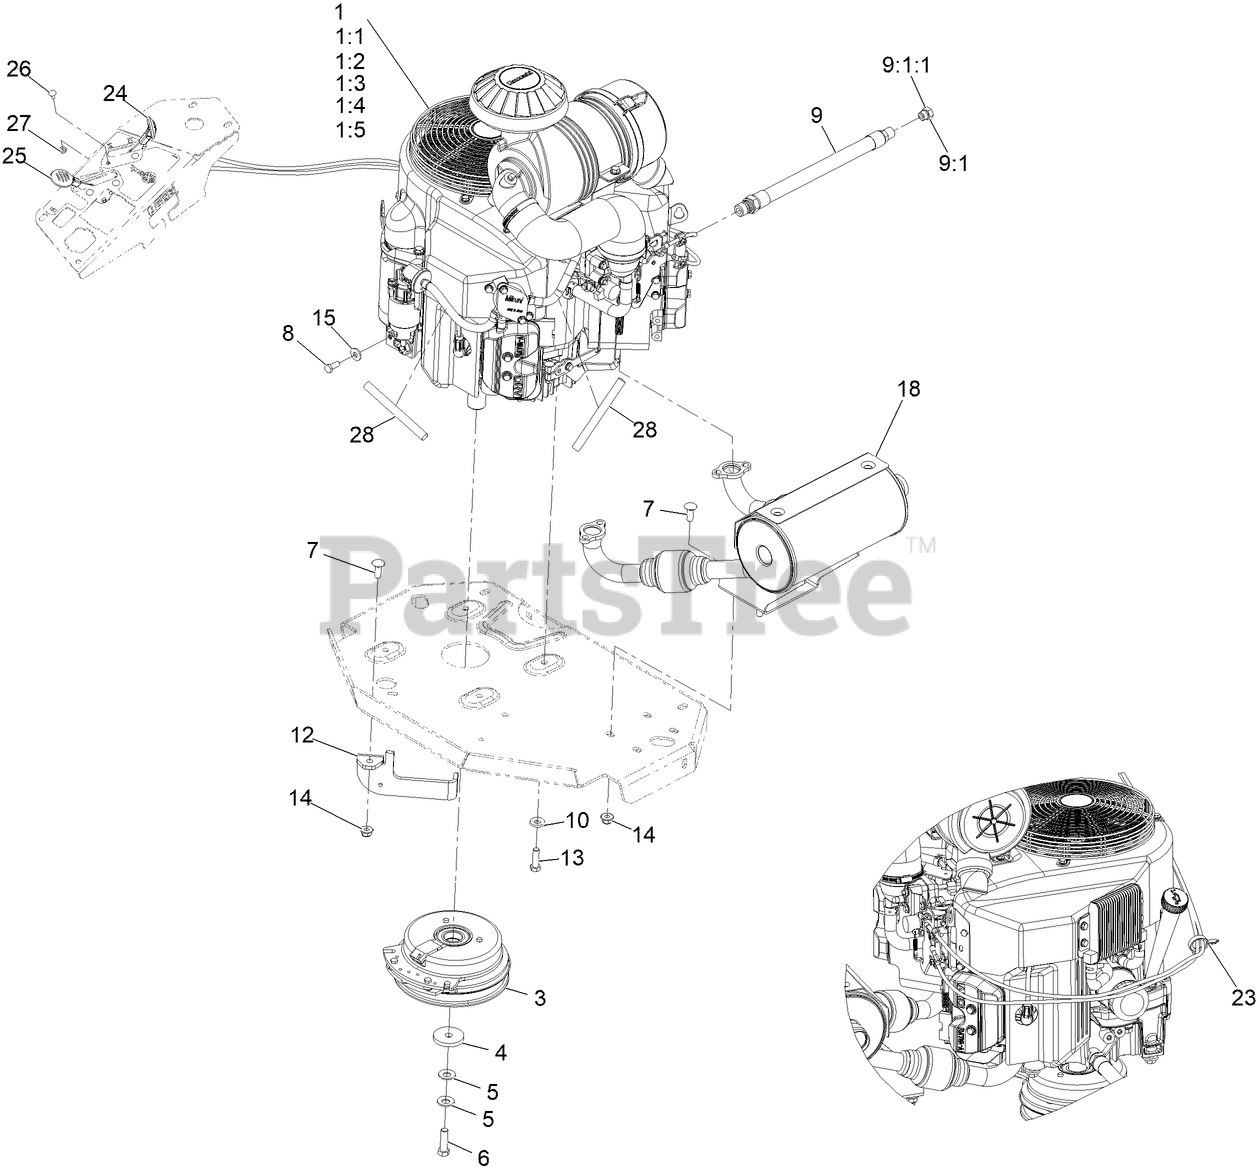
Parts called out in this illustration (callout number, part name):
1	Engine-Kawasaki
1:1	FILTER-OIL KAW
1:2	ELEMENT-FILTER, AIR (OUTE
1:3	ELEMENT-FILTER, AIR (INNE
1:4	FILTER-FUEL
1:5	SPARK PLUG
3	CLUTCH KIT
4	WASHER-CLUTCH
5	WASHER-SPRING
6	SCREW-HH 7/16-20 X 1 1/2 W/LOCTITE
7	SCREW-CARR
8	SCREW-HH
9	ENGINE OIL DRAIN HOSE ASM
9:1	PLUG-HH
9:1:1	O-RING
10	WASHER-BELLEVILLE
12	Bracket-Clutch Anchor
13	SCREW-HH
14	NUT-HF, NI
15	WASHER-SPRING
18	KIT, MUFFLER
23	CLAMP-HOSE
24	ASM, CHOKE CABLE
25	ASM,THROTTLE CABLE
26	BOLT-CARR
27	NUT-LOCK, NI
28	Sleeve-Thermal, Wrap
